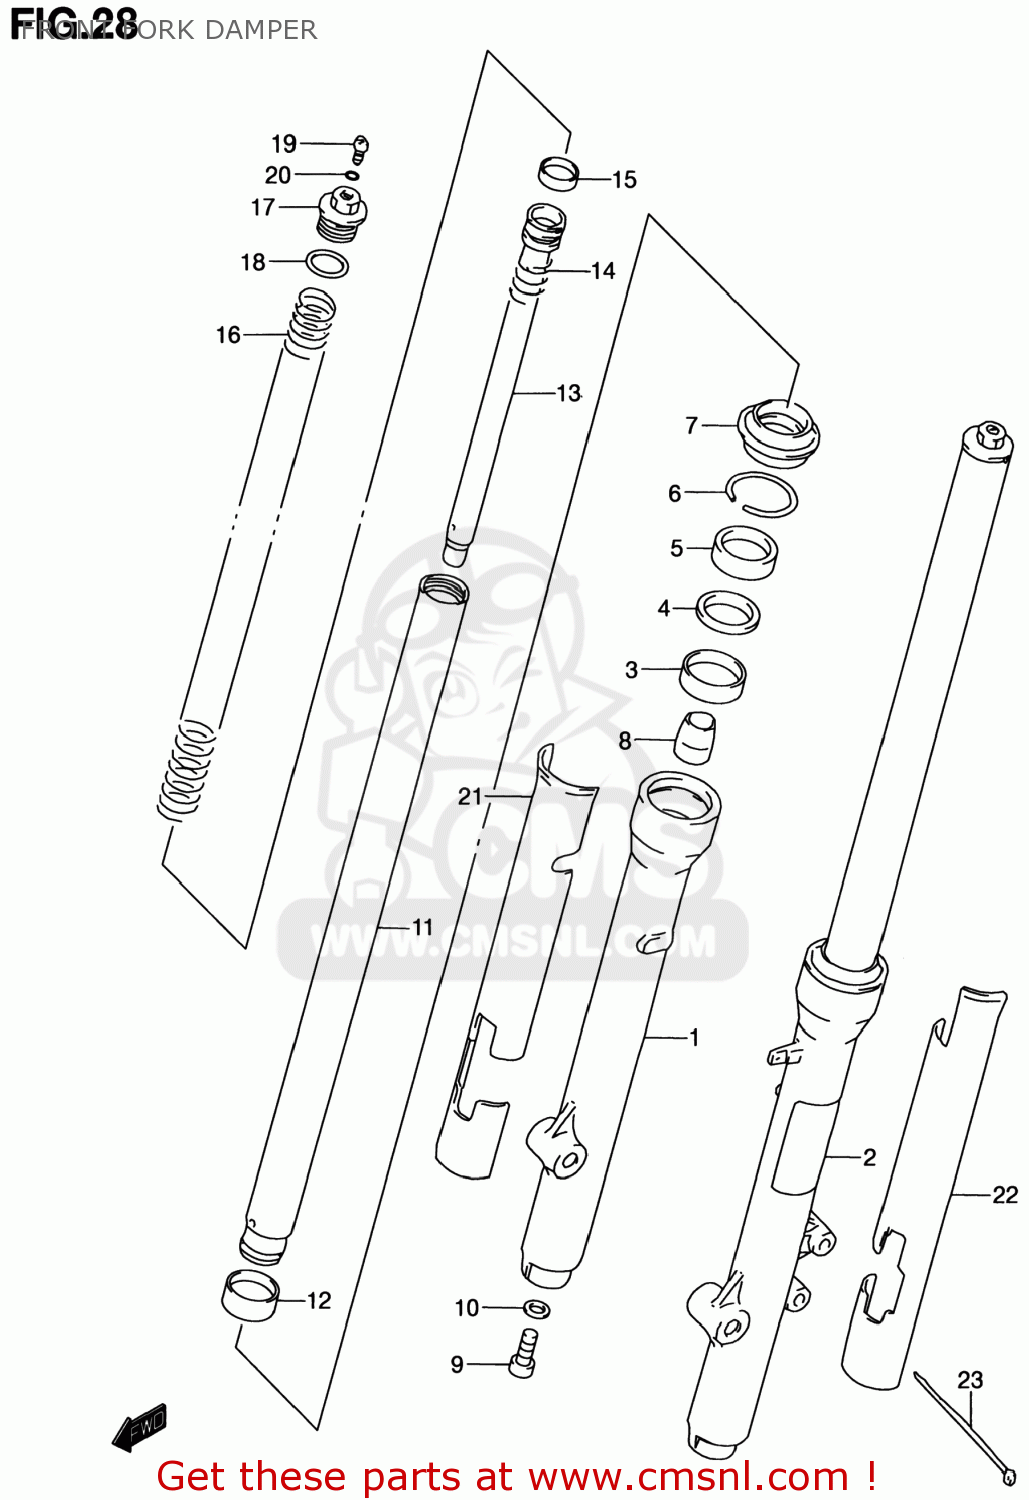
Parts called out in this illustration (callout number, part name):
1	TUBE,OUTER,R
2	TUBE,OUTER,L
3	BUSH,GUIDE
4	SPACER,SEAL
5	SEAL,OIL 35X48X11
6	RING,OIL SEAL STOPPER
7	SEAL,DUST
8	PIECE,OIL LOCK
9	BOLT(8X27)
10	GASKET (NAS)
11	TUBE,INNER
12	PISTON
13	SEAT,UNDER
14	SPRING,REBOUND
15	RING,PISTON
16	SPRING,UNDER
16A	SPRING, FRONT (HARD, K=0.36)
17	BOLT,FORK
18	O RING
19	BOLT,PLUG
20	O RING
21	PROTECTOR,FR FORK,R
22	PROTECTOR,FR FORK,L
23	CLAMP(L:250)
